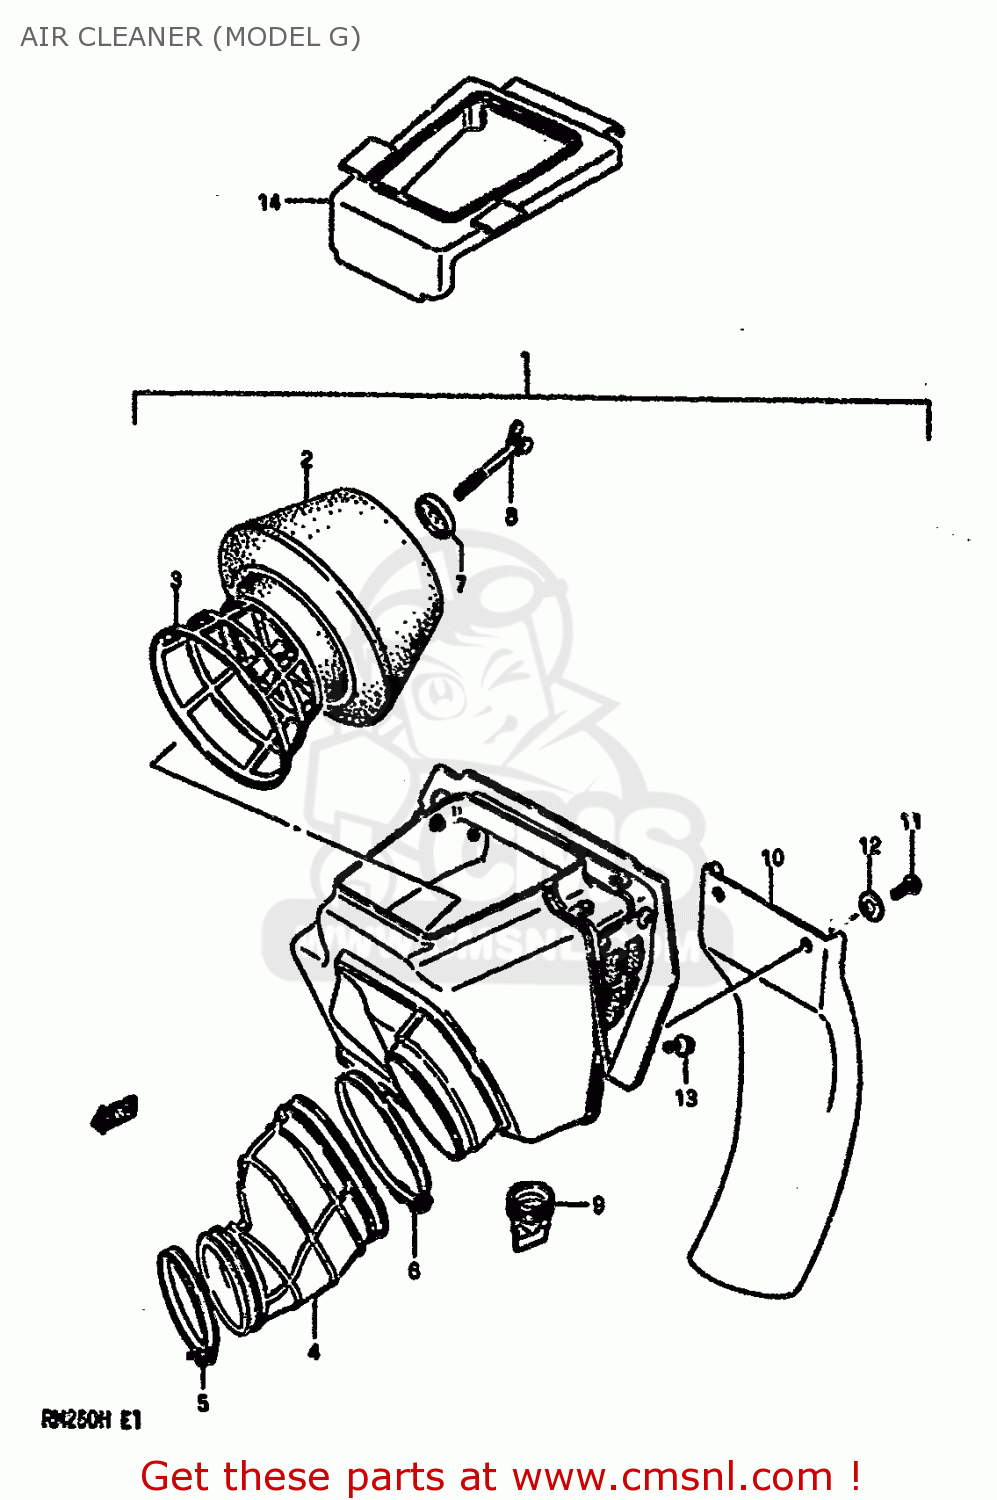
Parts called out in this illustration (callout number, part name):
1	CLEANER ASSEMBLY,AIR
2	FILTER
3	HOLDER,FILTER
4	TUBE,AIR CLEANER OUTLET
5	CLAMP
6	CLAMP
7	WASHER,AIR CLEANER
8	BOLT,WING
9	HOSE,AIR CLEANER DRAIN
10	GUARD,MUD
11	SCREW
12	COLLAR
13	BOLT
14	GUARD,MUD
